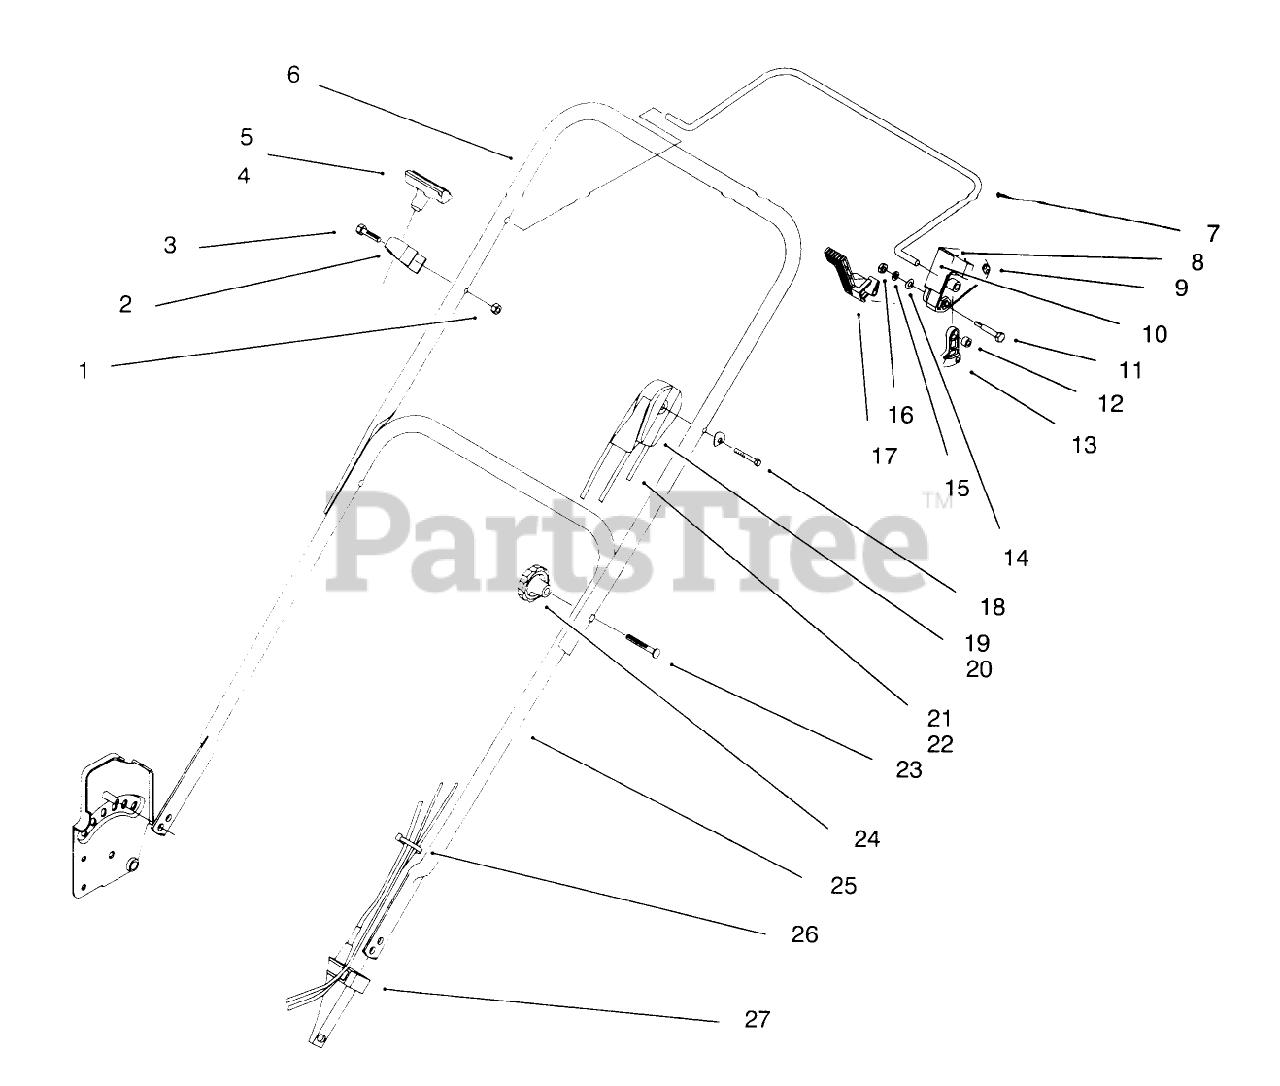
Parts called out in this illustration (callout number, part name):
1	NUT-LOCK, NI
3	SCREW-HH
5	CLIP-STARTER
9	STOP - PIVOT, PLASTIC
11	SHOULDER BOLT
12	SPACER-LEVER, TRACTION
13	LEVER-TRACTION
14	WASHER - SPRING
15	WASHER-PLAIN
16	NUT-LOCK, NI
17	LEVER - SHIFT
18	WASHER - CURVED
19	CABLE - THROTTLE/TRACTION
20	CABLE - THROTTLE/TRACTION
21	CABLE - BRAKE
22	CABLE - BRAKE
23	SCREW-HANDLE
26	TIE-CABLE
27	ANCHOR-CABLE
